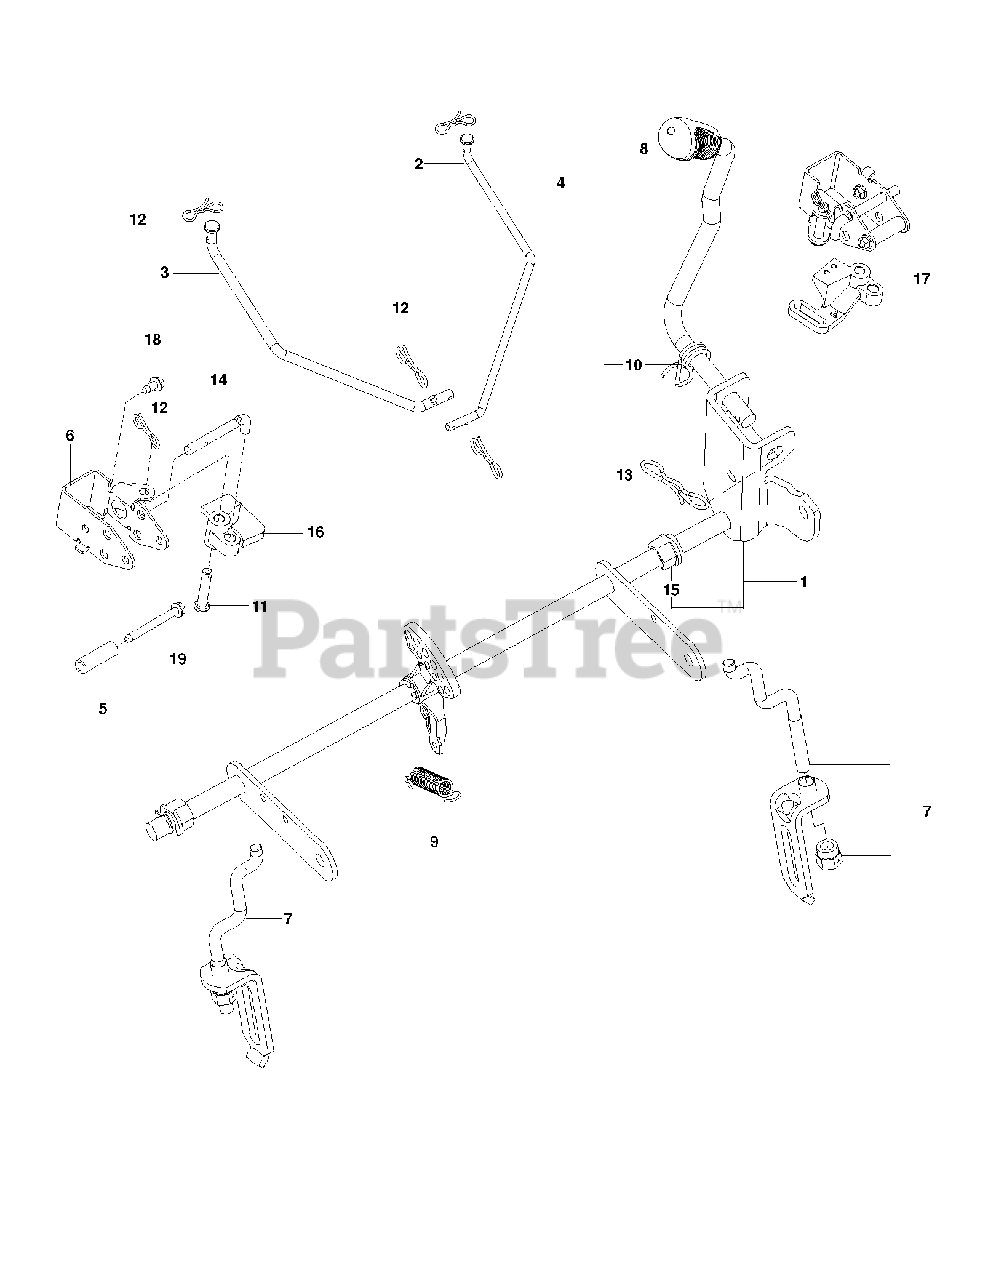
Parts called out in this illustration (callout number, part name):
1	SHAFT.ASM.RZ.DECK.LIFT.SRV
2	LINK.BRAKE.PARK.UPPER.LH
3	LINK.BRAKE.PARK.UPPER.RH
4	LIFT.LEVER.ASM.RZ.SERVICE
5	SPACER.334.ID.5.OD.1.5.L
6	BRACKET.BELLCRANK.PBRAKE X431
7	LINK.ASM.RZ.LIFT.SERVICE
8	GRIP.HANDLE.LIFT.PVC.BLACK
9	RETURN.BRAKE.PARK.AUTO
10	SPRING.TORSION.LIFT.HANDLE
11	PIN.5.16X1.5
12	PIN COTTER;LOCKING;BOWTIE;1IN
13	PIN.COTTER.7/16.BOW TI.
14	ROD.PUSH.BRAKE
15	PLASTIC NUT
16	BELLCRANK.RH
17	BELLCRANK.LH
18	SCREW.1/4-20X5/8
19	SCREW THD;ROLL;1/4-20 X 2.25
